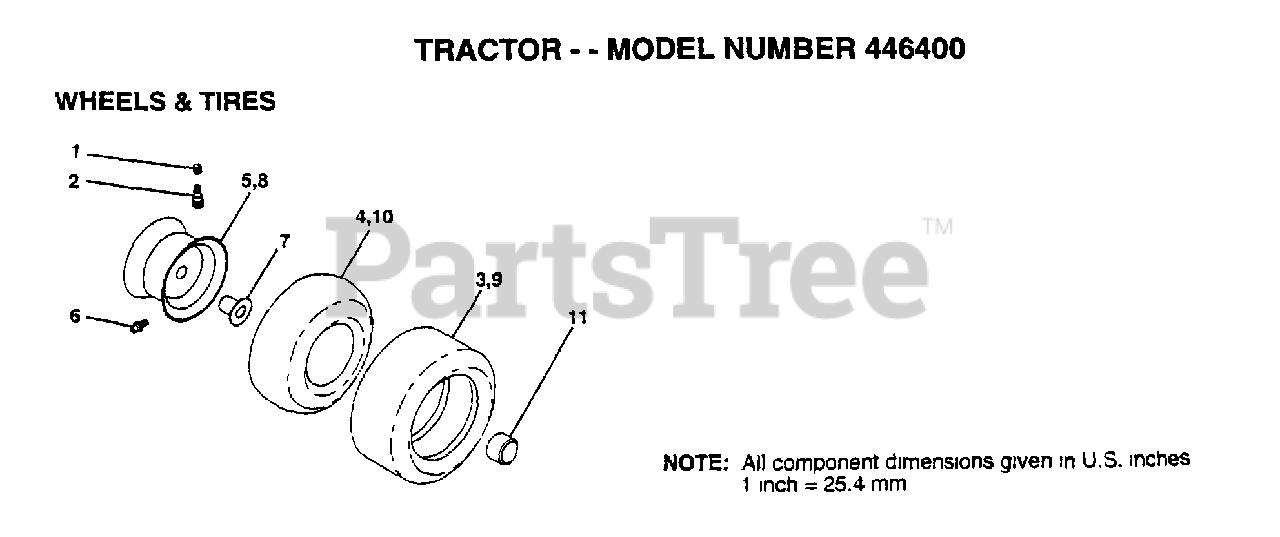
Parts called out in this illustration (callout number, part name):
1	VALVE CAP
2	VALVE STEM LT
4	TUBE.5.3/4.5/6
5	"RIM,FRT T"
6	FITTING LT
7	"FLANGE, BEARING"
8	"RIM 8"""
10	TUBE.18X9.5-8
11	HUB CAP
